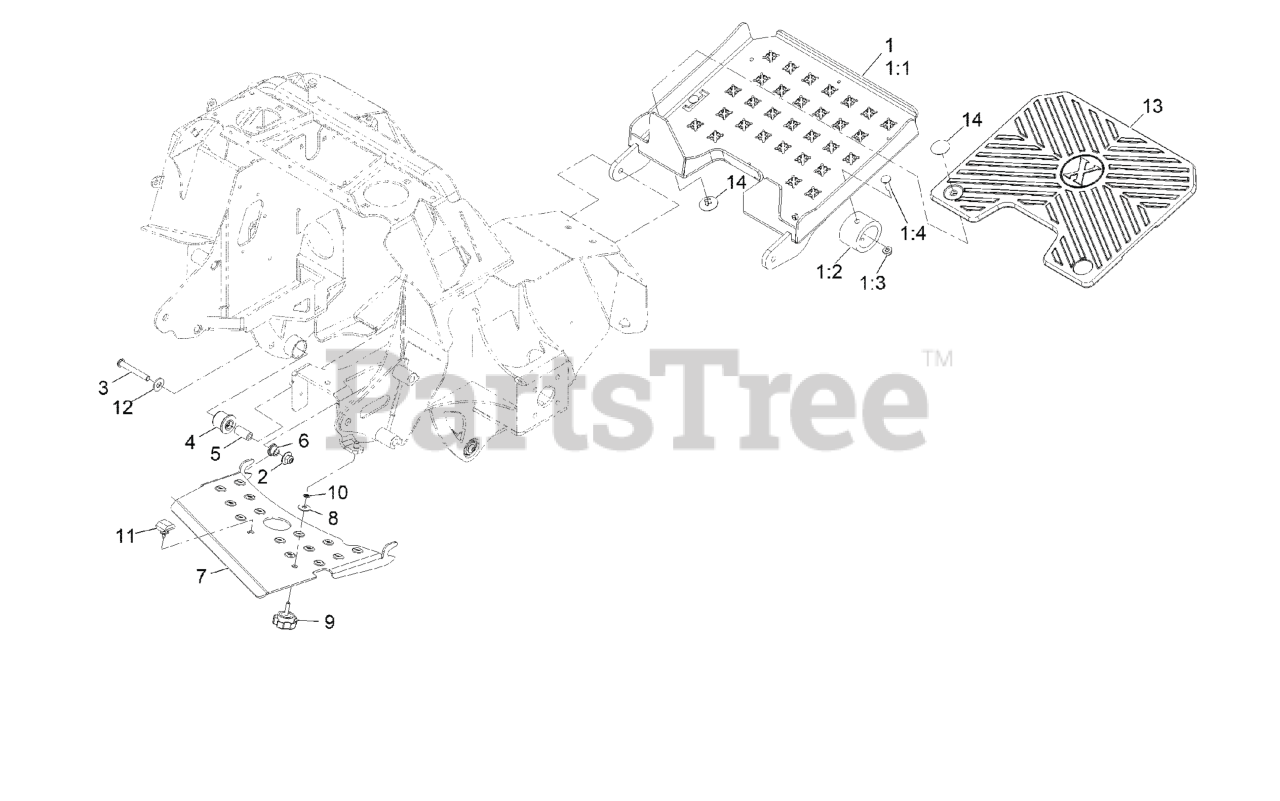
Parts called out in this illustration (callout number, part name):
1	ASM-PLATFORM
1:1	WELD-PLATFORM
1:2	BUMPER-ISOLATOR
1:3	NUT-HF, NI
1:4	BOLT-CARR
2	Nut-Nyloc 3/8-16 Flg
3	SCREW-HSBH
4	BUSHING-RUBBER, SUSPENSION
6	BUSHING-FLANGED
7	DEFLECTOR, AIR, 32
8	WASHER-BELLEVILLE
10	NUT-RETAINING
11	BUMPER-ROPS
12	WASHER-FLAT
13	PAD-PLATFORM
14	RIVET-RATCHET
